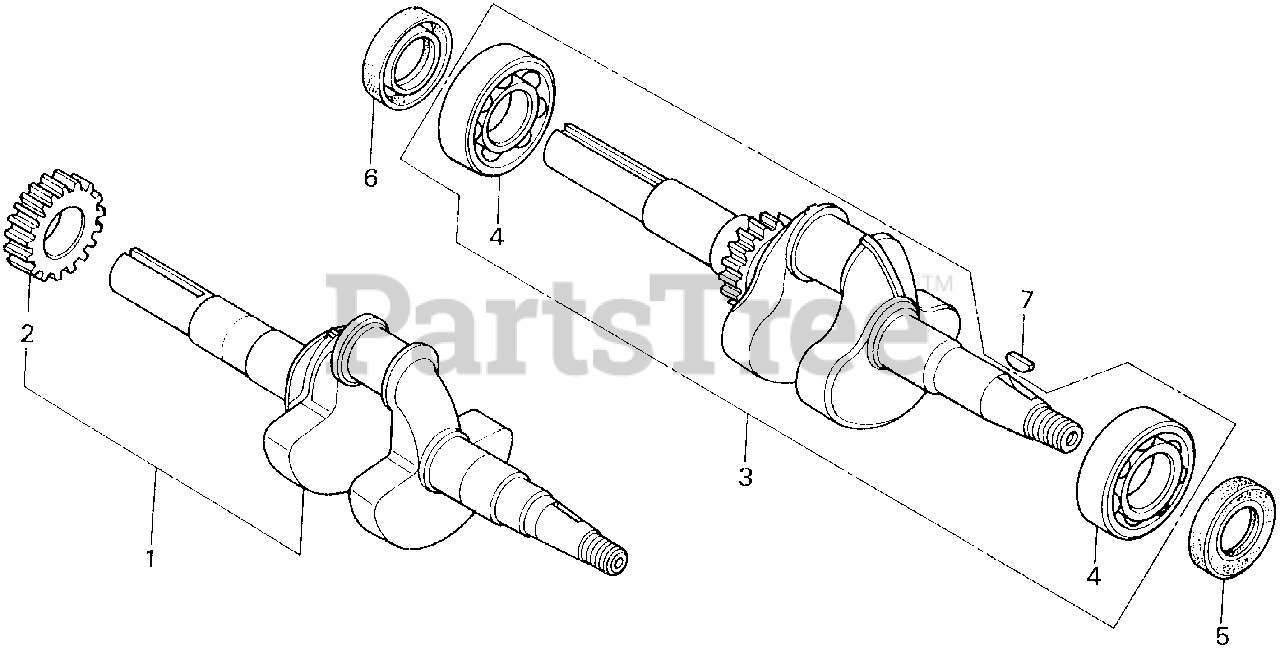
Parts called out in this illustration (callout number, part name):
3	CRANKSHAFT
4	BEARING, RADIAL BALL (62/22)
5	OIL SEAL (22X35X6)
6	OIL SEAL (22X41X6)
7	KEY, WOODRUFF (25X14)
